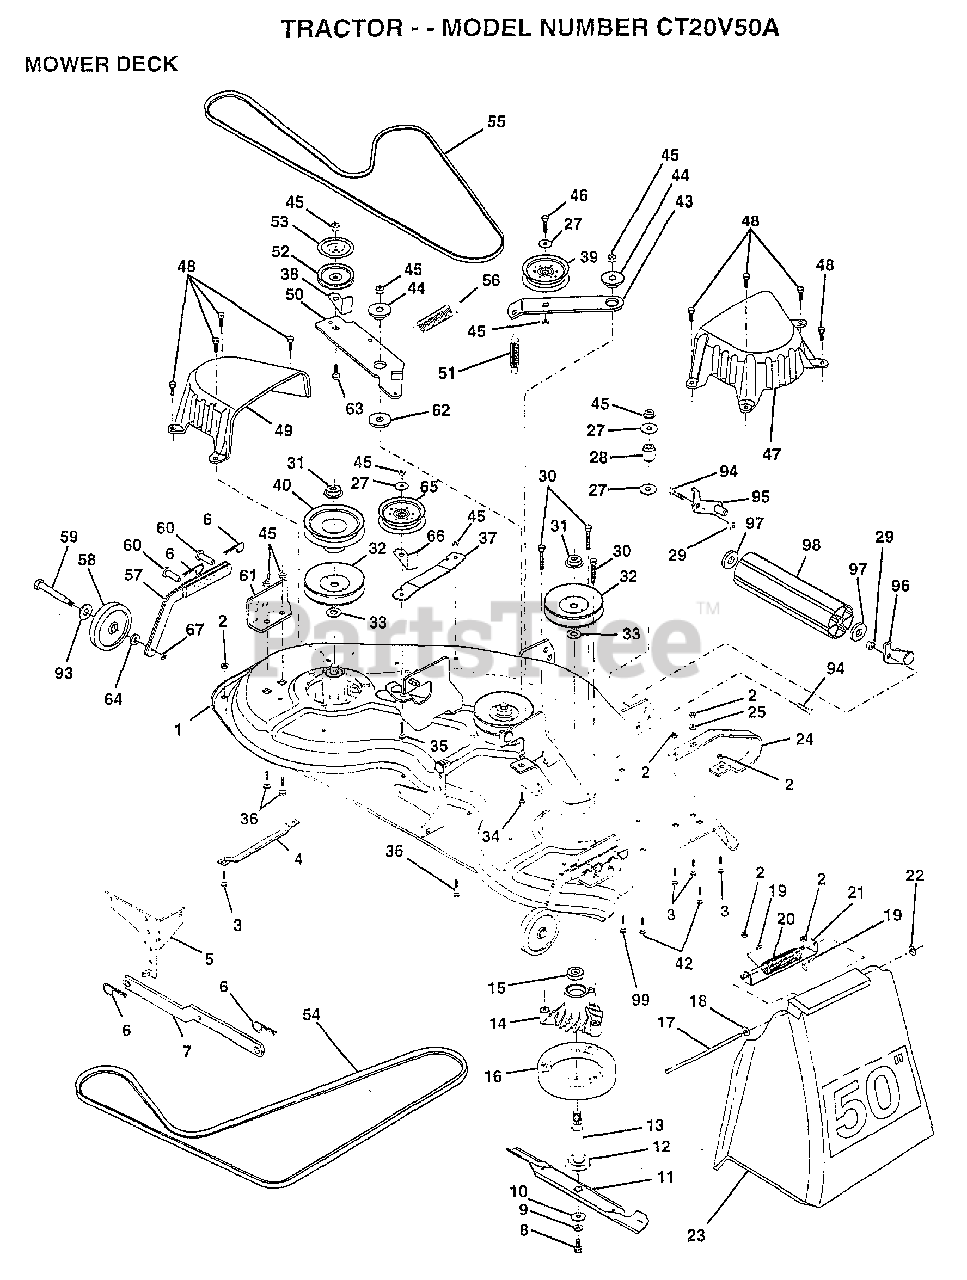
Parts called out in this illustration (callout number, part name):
1	DECK ASM MWR 50VT
4	RUNNER-LH M
5	BRKT.ASM.SW.44/50
8	BLADE BOLT
10	WASHER.HARD.BLADE
11	"BLADE.50"" HD"
12	BEARING.BALL
13	SHAFT.ASM.W/BRNG
14	HOUSING.MAND.44.V
15	BEARING
16	STRIPPER RND MWR
17	ROD-HINGE T
18	WASHER
20	SPRING TORSION
21	BRKT DEFLECTOR
23	DEFLECTOR
24	"RUNNER RH 50"" DK"
25	WASHER M
27	WASHER
29	NUT
33	WASHER
34	BOLT.3/8-14X1.25
35	BOLT
36	BOLT D
37	STIFFENER.ARM.IDL
39	FLAT IDLER PULLEY
40	"PULLEY.DRIVEN.44"""
42	BOLT
43	"ARM.IDLER.SEC.44"""
44	SPACER RETAINER
47	"COVER.MAND.RH.44"""
48	SCREW.1/4-20X5/8
49	COVER.MANDREL.LH
50	ARM.IDLER.PRIMARY
51	"SPRING.SEC.44""VEN"
52	PULLEY.IDLER.VGRO
53	SHIELD.IDLER.44.V
54	BELT V PRIM 50
55	BELT-V.SEC.46.KEL
56	SPRING.EXT.DECK.
57	BAR.ASM.GUAGE.WHL
58	WHEEL.GAGE.BLK.PL
59	BOLT M
60	PIN.CLEVIS
61	BRACKET.GUAGE.WHL
62	HARDENED WASHER
63	BOLT.3/8-16X1.50
64	WASHER
65	IDLER-FLAT T
67	LOCKNUT
93	WASHER
94	BOLT
97	WASHER
99	BOLT
